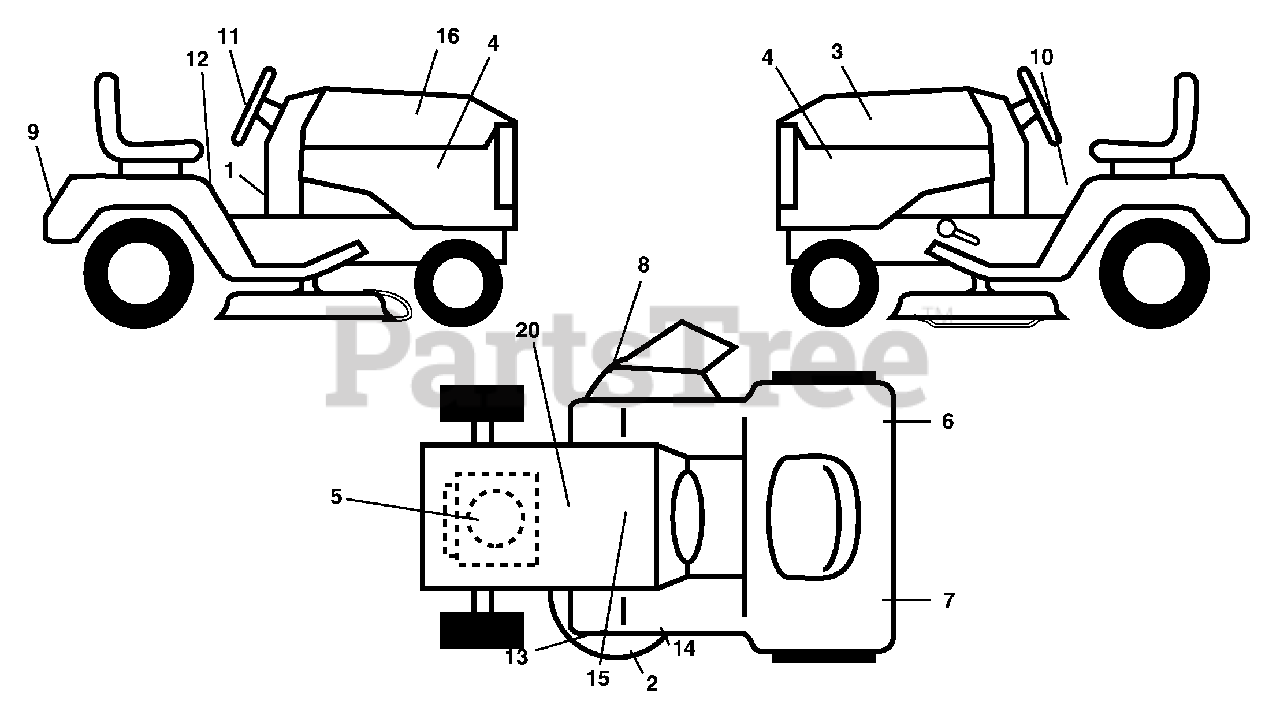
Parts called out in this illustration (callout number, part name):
1	Decal Dash
2	Decal Heavy Duty
3	Decal Hood LH
4	Decal Side Panel
5	Decal Engine
6	Decal Reflector Rh
7	Decal Reflector Lh
8	Decal Warning Mower
9	Decal Fender Logo
10	Decal Fender Danger E/F
11	Decal Ins Strg Whl
12	Decal Fender Oper
13	Decal Deck Caution
14	Decal V-Belt Schematic
15	Decal Replacement
16	Decal Hood Rh
20	Decal Bat Dan/Psn
